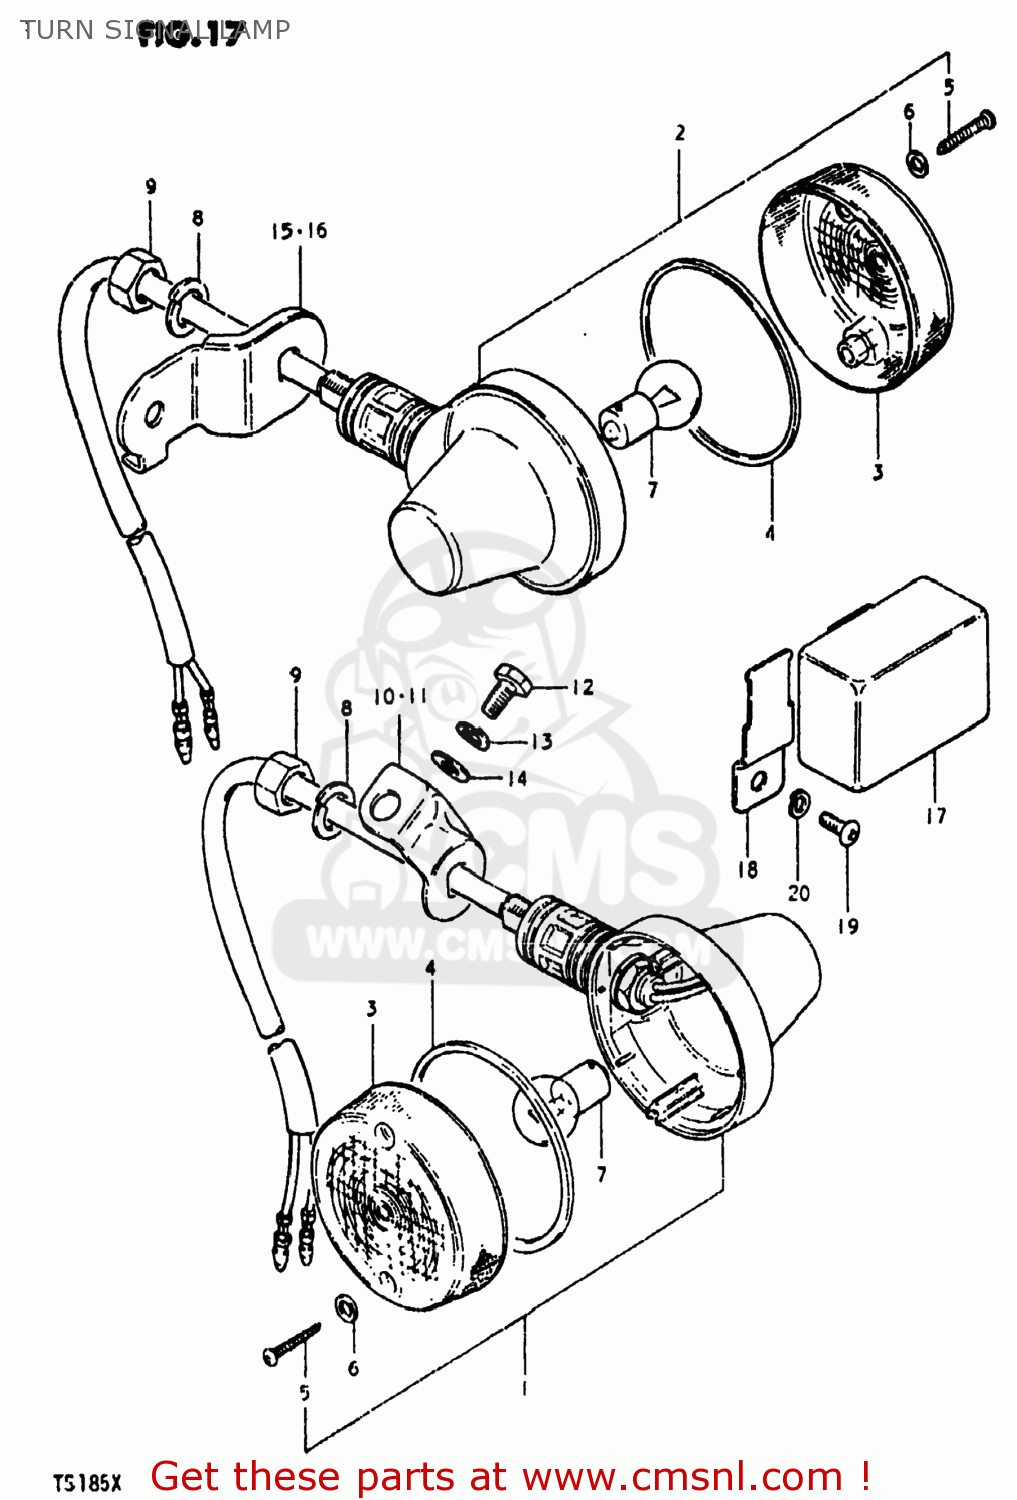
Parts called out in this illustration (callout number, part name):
1	LAMP ASSY,RR TURNSIGNAL
2	LAMP ASSY,RR TURNSIGNAL
3	LENS
4	GASKET (NAS)
5	SCREW TAPP.
6	GASKET (NAS)
7	BULB(6V17W,STANLEY,A4513A)
8	WASHER,LOCK 12
9	NUT
10	BRACKET,TURN SIGNAL LAMP
11	BRACKET,TURN SIGNAL LAMP
12	BOLT
13	LOCK WASHER
14	WASHER
15	BRACKET,REAR TURN SIGNAL
16	BRACKET,REAR TURN SIGNAL
17	RELAY,TURN SIGNAL
18	BRACKET,TURN SIGNAL RELAY
19	SCREW 6X12
20	LOCK WASHER
